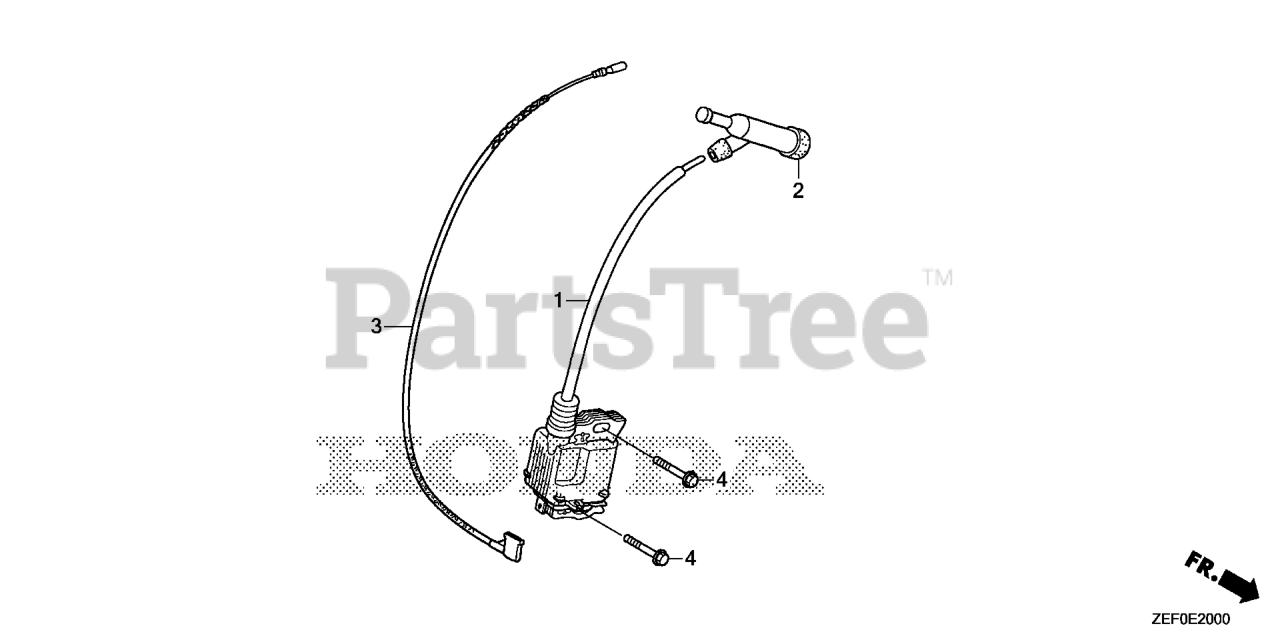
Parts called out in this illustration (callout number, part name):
1	COIL ASSY., IGNITION
2	CAP ASSY., NOISE SUPPRESSOR
3	WIRE, STOP SWITCH (370MM)
4	BOLT, FLANGE (6X25) Use up to Engine SN 2056819.
